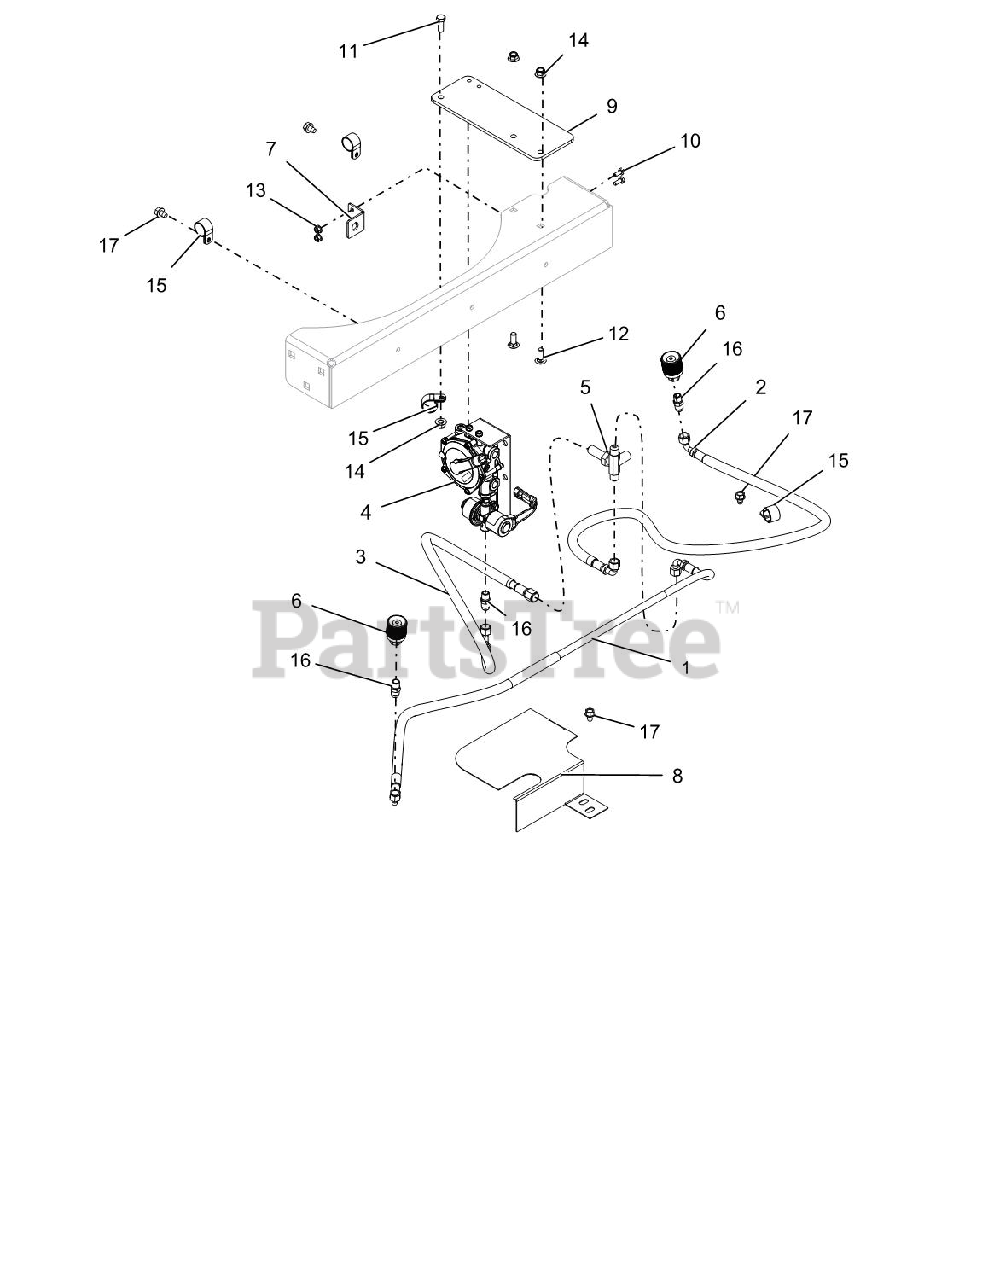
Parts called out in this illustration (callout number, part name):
1	HOSE, LPG SS25UL-6-4-6-45"
2	HOSE, LPG SS25UL 6-4-6-45"
3	HOSE, LPG SS25UL 6-4-6-30.00
4	SEE ENGINE SERVICE PARTS
5	VALVE, SHERWOOD T PV3866 LPG
6	FTG, LPG TANK COUPLER -LH THRD
7	BRKT, TEE VALVE- MOUNTING
8	GUARD, LP-MUFFLER-BLACK
9	PLATE, REGULATOR MOUNT, EG
10	BLT-HEX .25-20X.63 GR5 YWZC
11	BLT-HEX .38-16X1.00 GR5 YWZC
12	BLT-RDHDSQNK .38-16X1.00 G5 YWZC
13	NUT, LK-TOP-FLG .25-20 YWZC
14	NUT-LK-NYL-FLG .38-16 YWZC
15	CLAMP, CUSHIONED STEEL REV
16	FTG, ADPTR 1/4MNPT X 5/8MJIC
17	SCR-TAP .38-16X.50 HWH TR YWZ
